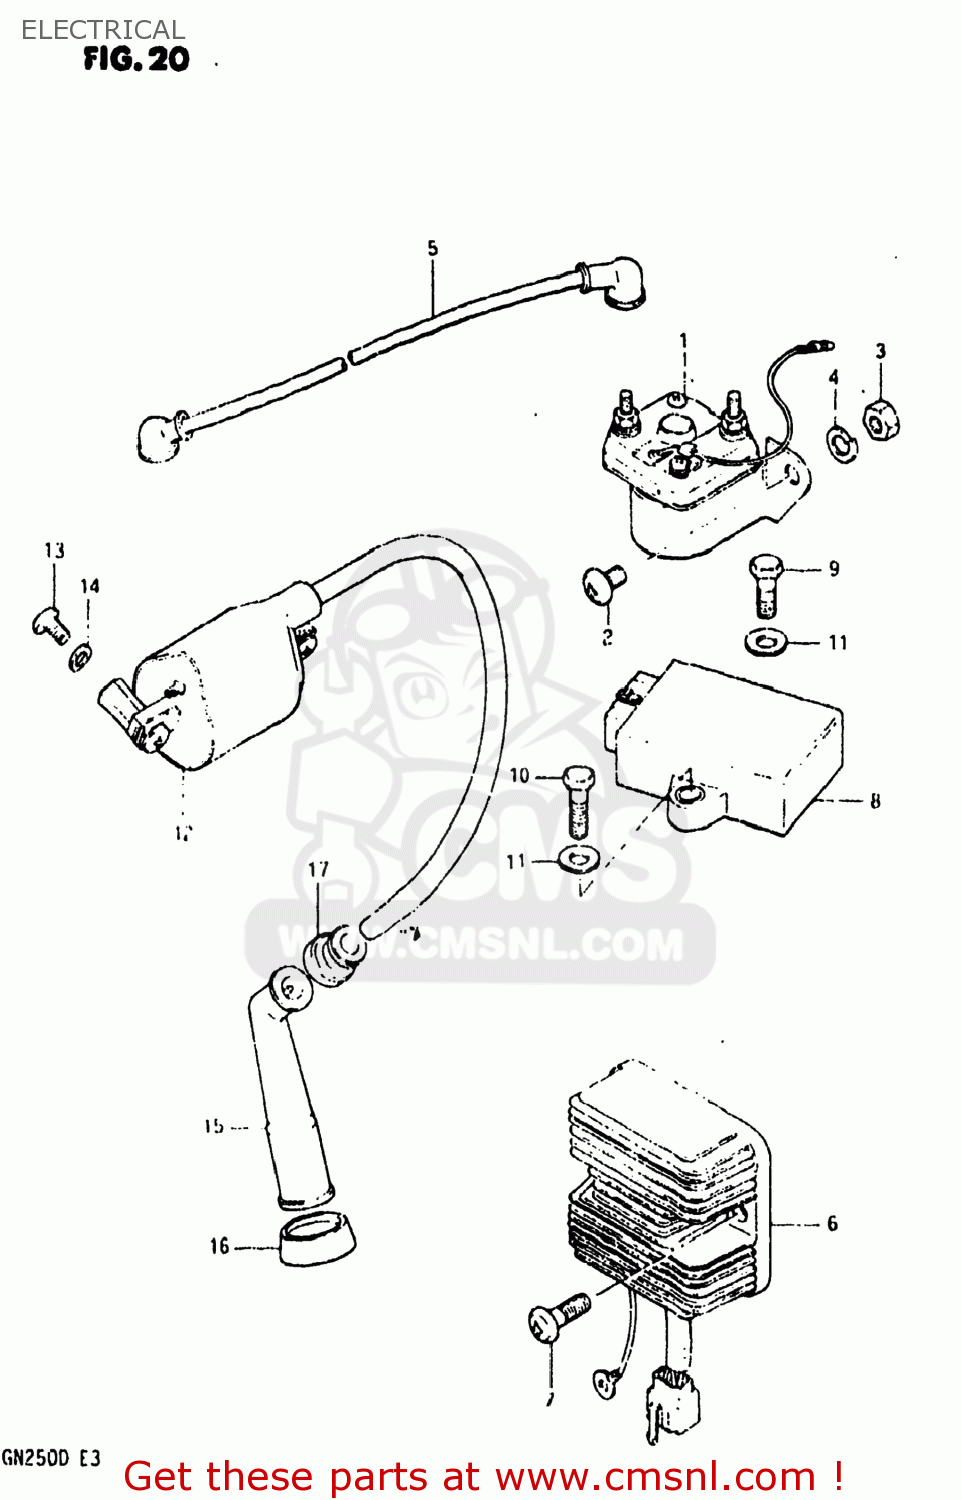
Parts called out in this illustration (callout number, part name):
1	RELAY ASSY,STARTING MOTOR
2	SCREW
3	NUT 6MM
4	LOCK WASHER
5	WIRE,STARTER MOTOR LEAD
6	RECTIFIER ASSEMBLY
7	SCREW(6X12)
8	IGNITOR UNIT
9	BOLT
10	BOLT
11	WASHER
12	COIL ASSY,IGNITION
13	SCREW
14	WASHER
15	CAP ASSY,SPARK PLUG
16	SEAL,SPARK PLUG
17	SEAL,SPARK PLU
